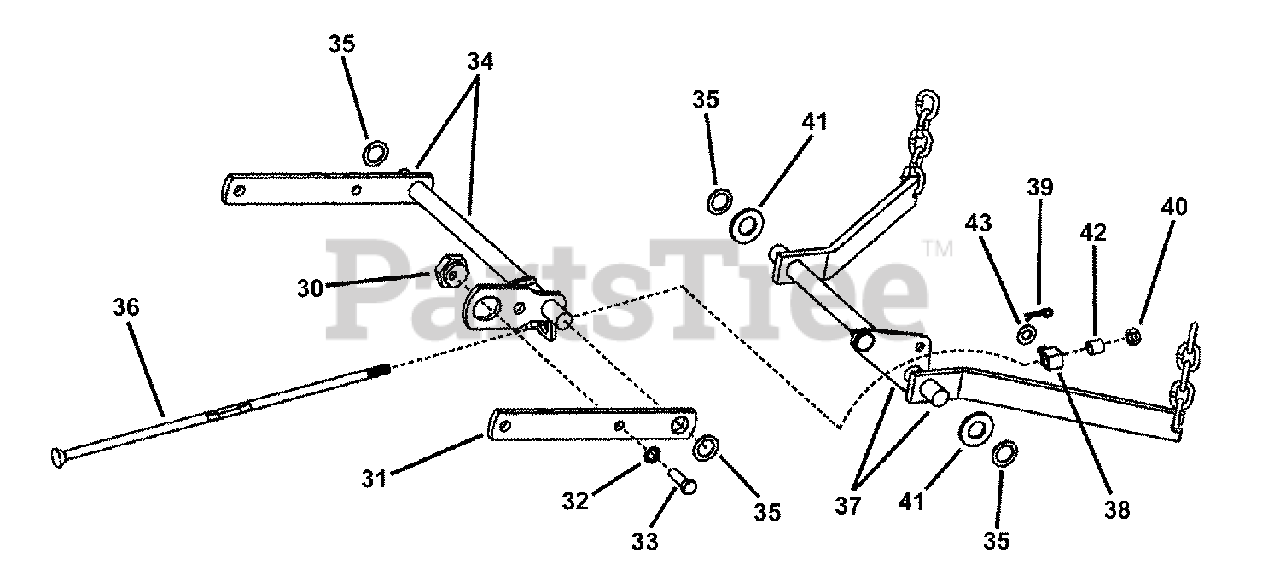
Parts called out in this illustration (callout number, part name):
30	ECCENTRIC, Leveling
31	LIFT ARM, Front
32	WASHER, 3/8" Internal Tooth Lock
33	SCREW, 3/8-24 x 1-1/4" Hex Head Cap w/Nylon Patch, GR5
34	WELDMENT, Lift Arm, Front
35	WASHER, 3/4" Flat
36	ROD, Cutter Deck Timing (3/8-16 thread)
37	WELDMENT, Lift Arm, Rear
38	SWIVEL, Brake Link- PM
39	HAIR PIN, #13
40	NUT, 3/8-16 Hex Center Lock
41	WASHER, .781 x 1.5 x .132 Flat
42	SPACER, .391 I.D. x .531 long
43	WASHER, .375 x .875 x .083 Flat
